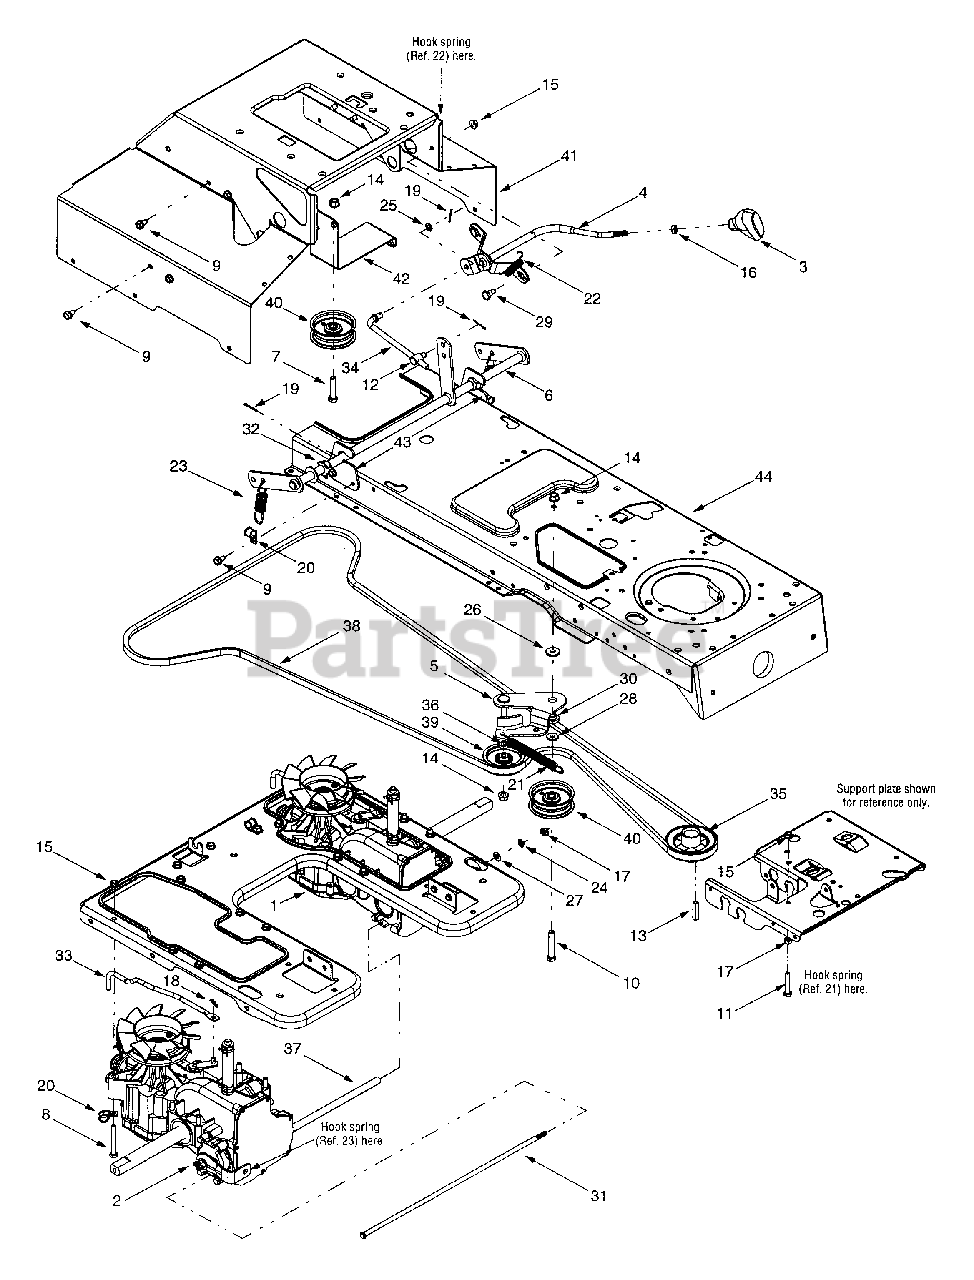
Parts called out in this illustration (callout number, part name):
1	LH IZT Transmission
2	RH IZT Transmission
3	Knob
4	Brake Lever Assembly
5	Double-idler Bracket
6	Brake Bracket Assembly
7	Hex Cap Screw, 3/8-16 x 1.75
8	Hex Cap Screw, 5/16-18 x 2.5
9	Self-tapping Screw, 5/16-18 x .625
10	Hex Cap Screw, 3/8-16 x 2.25
11	Hex Cap Screw, 5/16-18 x 1.75
12	Ferrule, 3/8-24 x .375
13	Square Key, 1/4 x 1.5
14	Flange Lock Nut, 3/8-16
15	Flange Lock Nut, 5/16-18
16	Jam Nut, 3/8-16
17	Hex Nut, 5/16-18
18	Internal Cotter Pin, .072 x 1.121
19	Cotter Pin, 3/32 x 1.0
20	Clamp, 9/16
21	Extension Spring, .62 x 6.12
22	Extension Spring, .5 x 2.75
23	Disc Brake Spring
24	Lock Washer, 5/16
25	Flat Washer, .385 x .62 x .063
26	Flat Washer, .385 x 1.0 x .135
27	Flat Washer, .344 x .688 x .065
28	Flat Washer, .407 x .812 x .135
29	Shoulder Screw, .435 x .350, 5/16-18
30	Shoulder Spacer, .380
31	Rod, .312 x 18.437
32	Split Hex Flange Bearing, .628
33	Hydro Bypass Rod
34	Brake Link Rod
35	Engine Pulley
36	Spacer, .376 x .625 x .220
37	Spacer, .334 x .50 x 14.88
38	Drive Belt, Poly
39	V-Idler Pulley, 3.06
40	Flat Idler, 2.75
